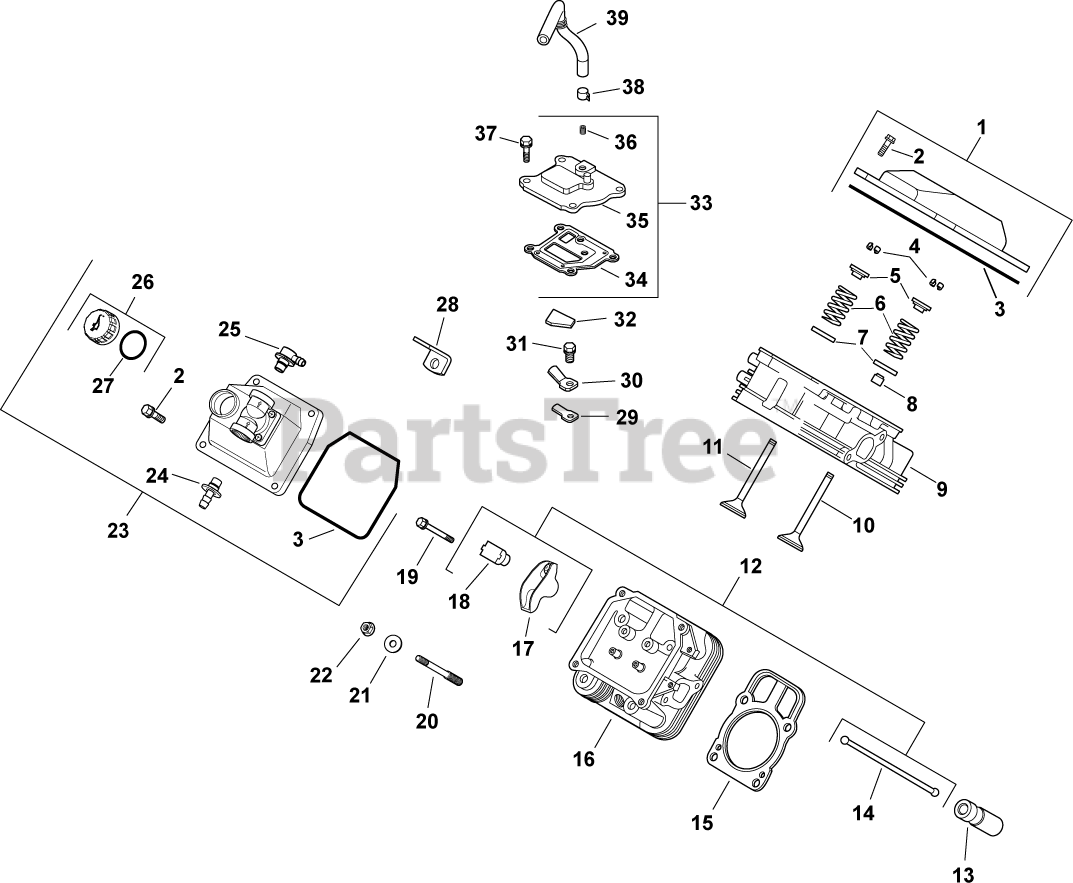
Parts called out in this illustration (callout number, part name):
1	KIT, VALVE COVER-PLAIN
2	SCREW, FLG M6X1.0X30
3	O-RING (YELLOW), VALVE COVER
4	KIT, RETAINER
5	RETAINER, VALVE SPRING - USE 25 173 28-S
6	SPRING, VALVE
7	RETAINER, SPRING
8	SEAL, VALVE STEM - (#2503214S)
9	KIT, CYLINDER HEAD #1 - (#24318143S)
10	VALVE, INTAKE (STD)
11	VALVE, EXHAUST (STD) - USE 32 016 01-S
12	KIT, VALVE TRAIN
13	LIFTER, HYDRAULIC VALVE-USE 25 351 10-S
14	ROD, PUSH
15	CYL HEAD GASKET KIT-USE 24 841 04-S
16	KIT, CYLINDER HEAD #2 USE 24 318 149-S
17	ARM, ROCKER
18	PIVOT, ROCKER ARM
19	SCREW, FLG M6X1.0X34
20	STUD, M8X1.25
21	WASHER, FLAT 8.6 MM
22	NUT, FLG M8X1.25
23	KIT, VALVE COVER-FUEL PUMP
24	KIT, STRAIGHT FITTING
25	KIT, 90 DEG. FITTING
26	CAP ASSY, OIL FILL (YELLOW)
27	O-RING-USE 24 153 32-S
28	STRAP, LIFTING-USE 25 445 03-S
29	REED, BREATHER
30	RETAINER, REED
31	SCREW, FLG THD FRM M5X.8X10
32	FILTER, BREATHER
33	KIT, BREATHER ASSEMBLY
34	GASKET, BREATHER-USE 24 041 67-S
35	COVER, BREATHER -USE 24 033 01-S
36	PLUG, CTSK PIPE 1/8"
37	SCREW,FLG THD FRM M6X1.0X20-(#25086396S)
38	CLAMP, HOSE (KM)-USE 25 237 31-S
39	HOSE, BREATHER
2401602-S	VALVE, EXHAUST (.25)
2401702-S	VALVE, INTAKE (.25)
